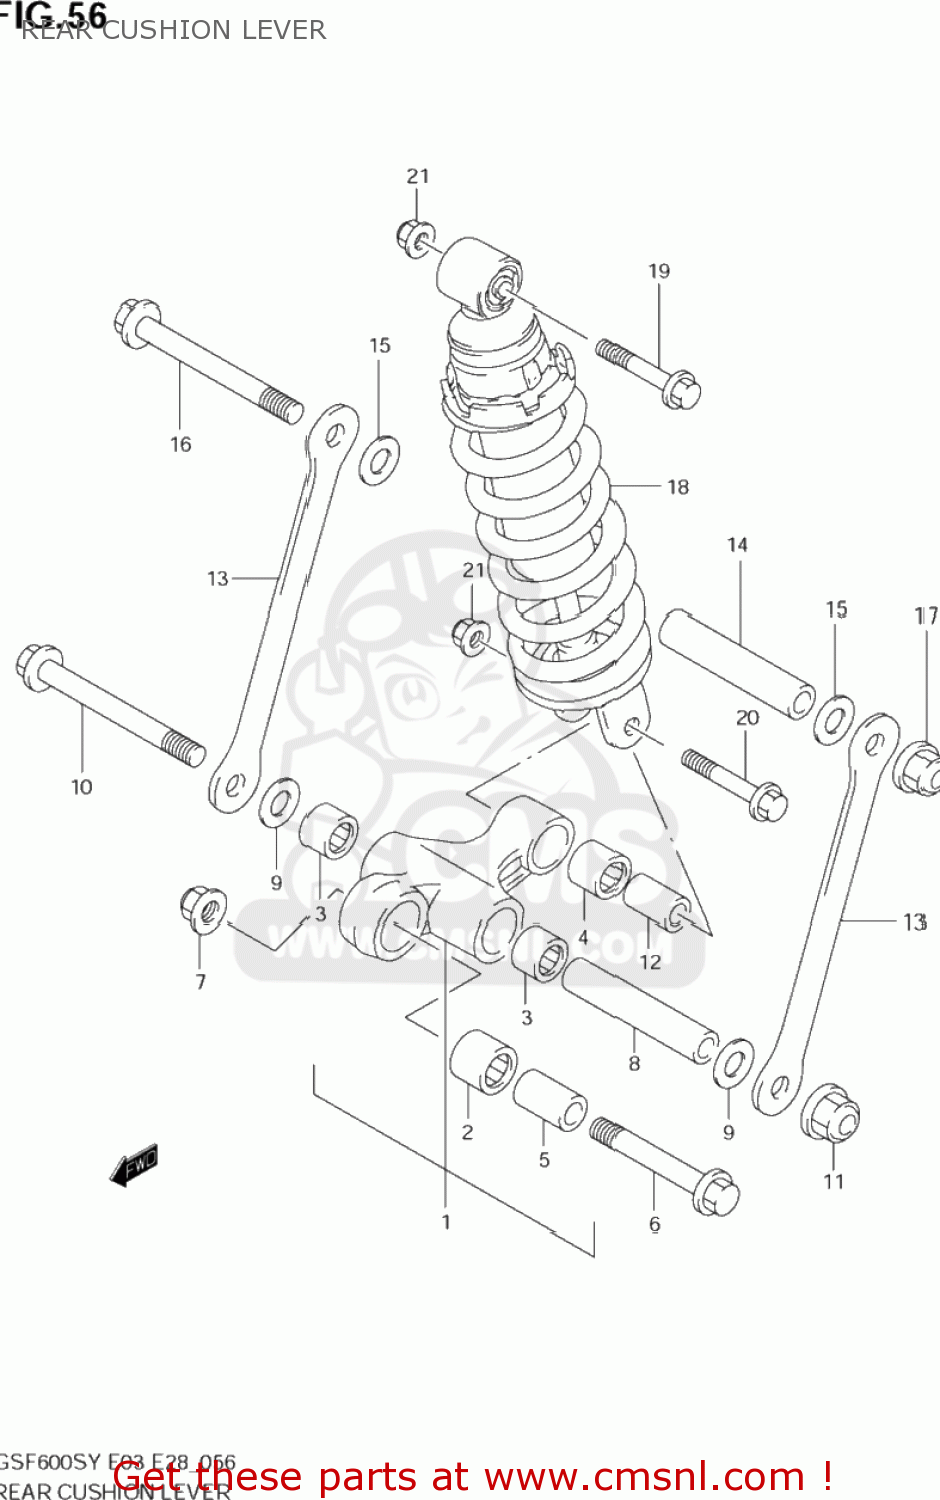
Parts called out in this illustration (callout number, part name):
1	LEVER SET,REAR CUSHION
2	BEARING(20X27X26)
3	BEARING(17X24X25)
4	BEARING(17X24X26)
5	SPACER,RR CUSHION LEVER FR
6	BOLT,CUSHION LEVER FR
7	NUT 12MM
8	SPACER(12X17X89)
9	WASHER(12X34X1)
10	BOLT,REAR CUSHION ROD
11	NUT 12MM
12	SPACER,RR CUSHION LEVER
13	ROD,RR CUSHION
14	SPACER(12X17X89)
15	WASHER(12X34X1)
16	BOLT,REAR CUSHION ROD
17	NUT 12MM
18	ABSORBER ASSY,RR SHOCK
19	BOLT,RR CUSHION ROD UPR
20	BOLT,RR SHOCK ABSORBER
21	NUT
